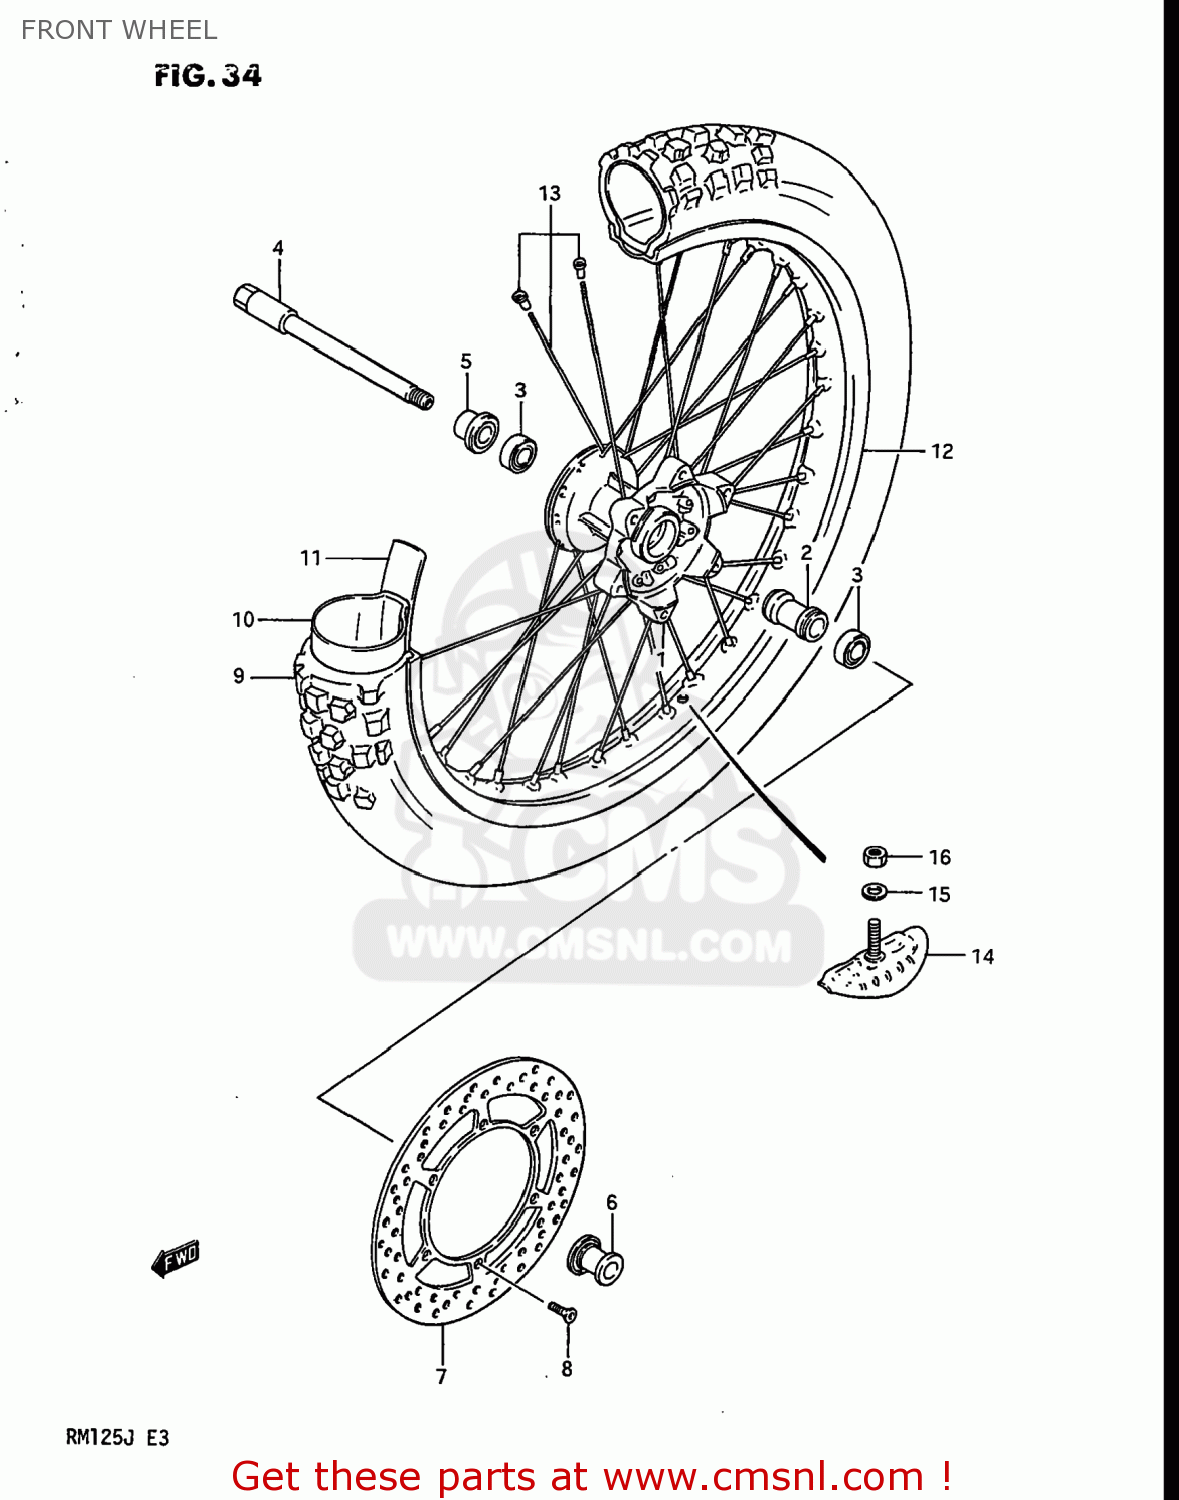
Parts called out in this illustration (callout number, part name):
1	HUB,FRONT
2	SPACER,FR HUB BEARING
3	BEARING
4	AXLE,FRONT
5	SPACER,FRONT AXLE,RIGHT
6	SPACER,FRONT AXLE,LEFT
7	DISC,BRAKE
8	SCREW
9	TIRE,FRONT
10	TUBE,INNER
11	PROTECTOR,WHEEL INNER
12	RIM,FRONT WHEEL
13	SPOKE SET,FRONT
14	STOPPER,BEAD
15	WASHER
16	NUT 8MM
